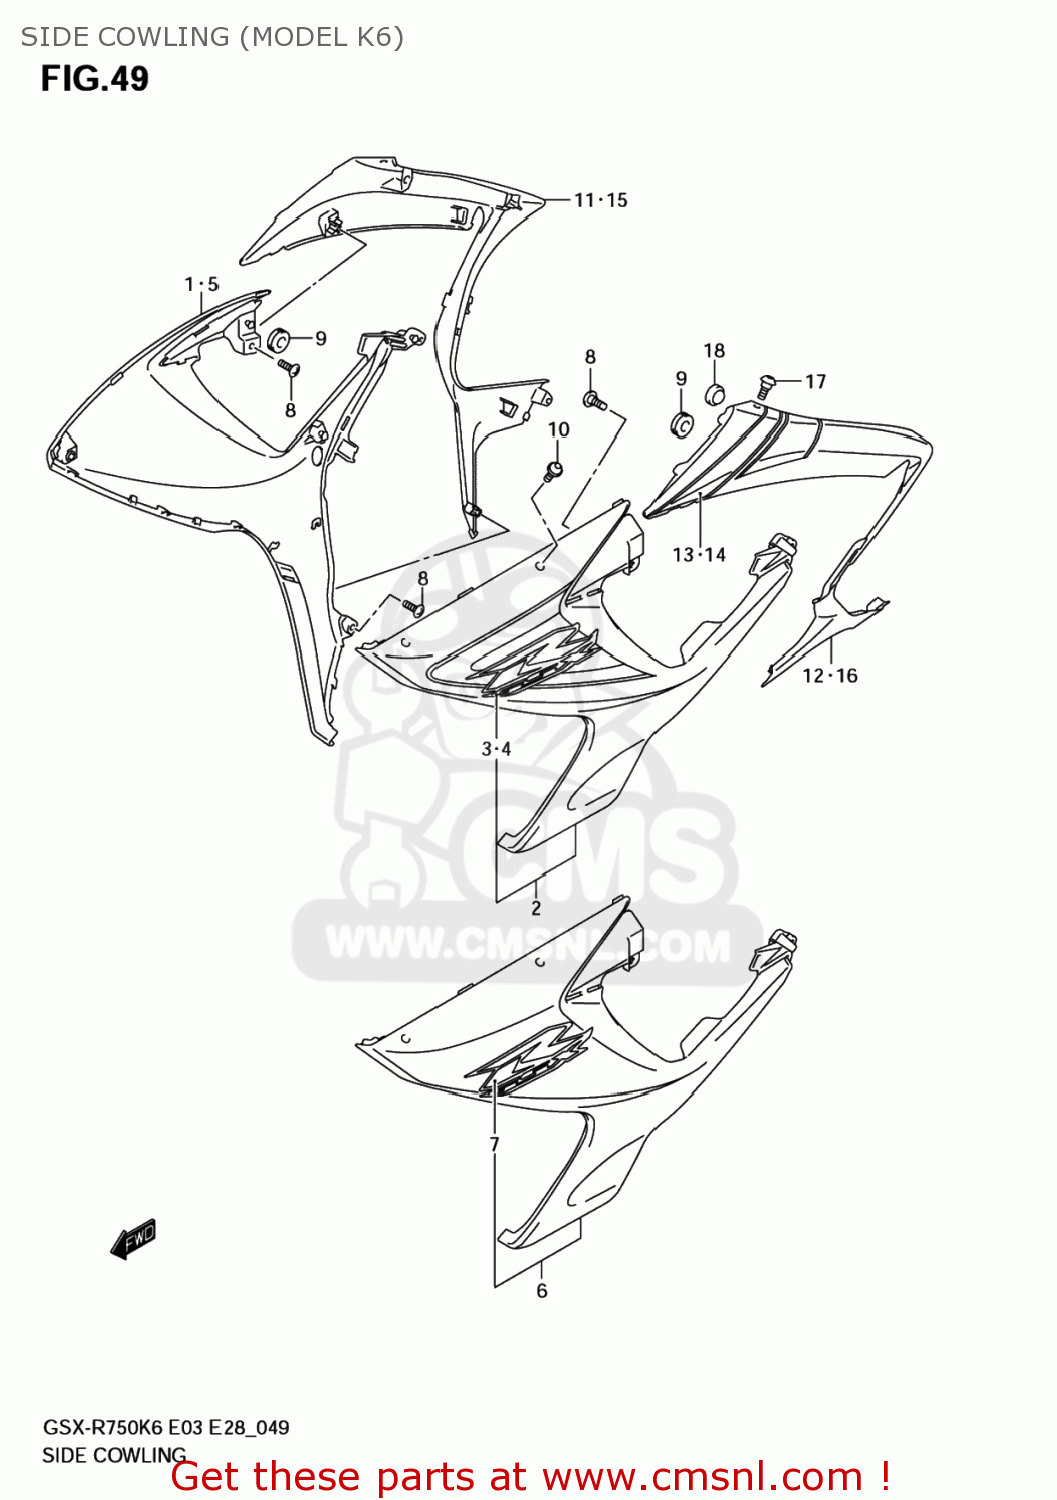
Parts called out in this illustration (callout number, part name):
1	COWLING,SIDE,R(BLACK)
2	COWLING,SIDE,L(BLACK)
3	TAPE,COWL SIDE,R
4	TAPE,COWL SIDE,L
5	COWLING,SIDE,R(BLACK)
6	COWLING,SIDE,L(BLACK)
7	EMBLEM,GSXR
8	SCREW
9	CUSHION
10	SCREW(5X13)
11	COVER,UNDER COWL,R(RED)
12	COVER,UNDER COWL,L(RED)
13	TAPE SET,COVER UNDER COWL,R
14	TAPE SET,COVER UNDER COWL,L
15	COVER,UNDER COWL,R
16	COVER,UNDER COWL,L
17	SCREW(5X16)
18	CUSHION
